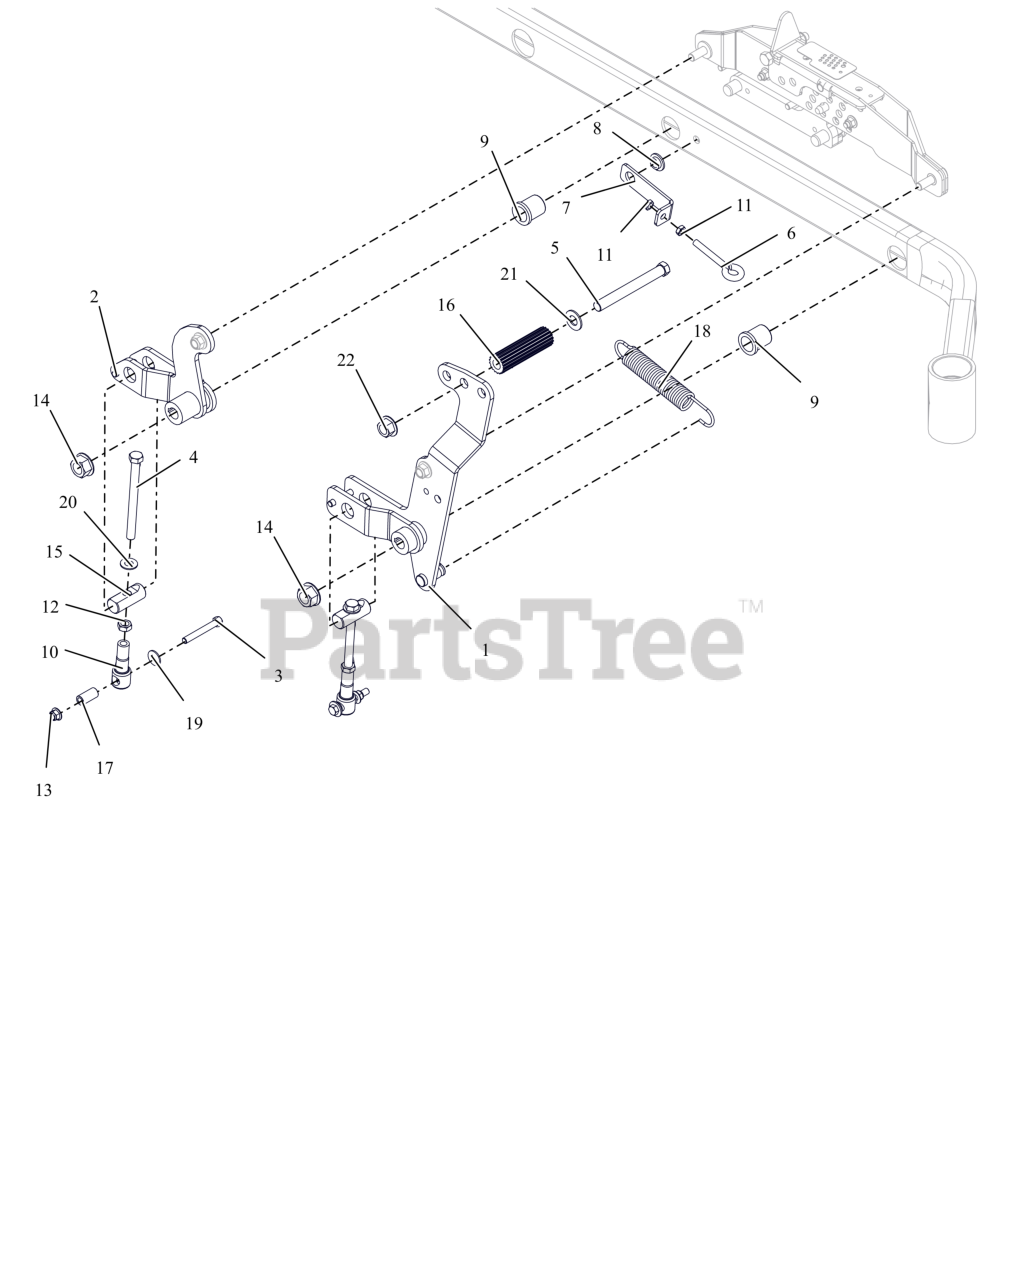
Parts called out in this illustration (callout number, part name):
1	FRT RH DECK LIFT ARM WMT- LF
2	REAR RH DECK LIFT ARM WMT- LF
3	BLT, HEX .38-16X2.75 G8 ZCC
4	BLT, HEX .50-13X6.00S G5 ZCC
5	BLT, HEX .62-11X5.50 G5 FBP
6	BLT-EYE .375-16X2.50 YWZC
7	SPRING ANCHOR BRACKET - RED
8	BSHG-FLG .515X.750X.310X1.120
9	BSHG-FLG 1.00X1.25X1.50X1.50
10	LINK, DECK LIFT FORMED
11	NUT-JAM .375-16 G2 ZCC
12	NUT-JAM .500-13 G2 ZCC
13	NUT,NYL-FLG .38-16 GF ZCC
14	NUT,FLG-TOP LK .625-11 FBP
15	PIN, DECK LIFT
16	ROD, FOOT PEDAL (BLACK)
17	SPACER, DECK LEVELING
18	SG-TENS .162X1.25X8.25 WLD 25
19	WSHR,FLT .438X1.00X.083 ZCC
20	WSHR, FLT .557X1.040X.102 ZCC
21	WSHRFLT 5/8SAE CARBHARD FBP
22	NUT,FLG-TOP LK .625-11 FBP
